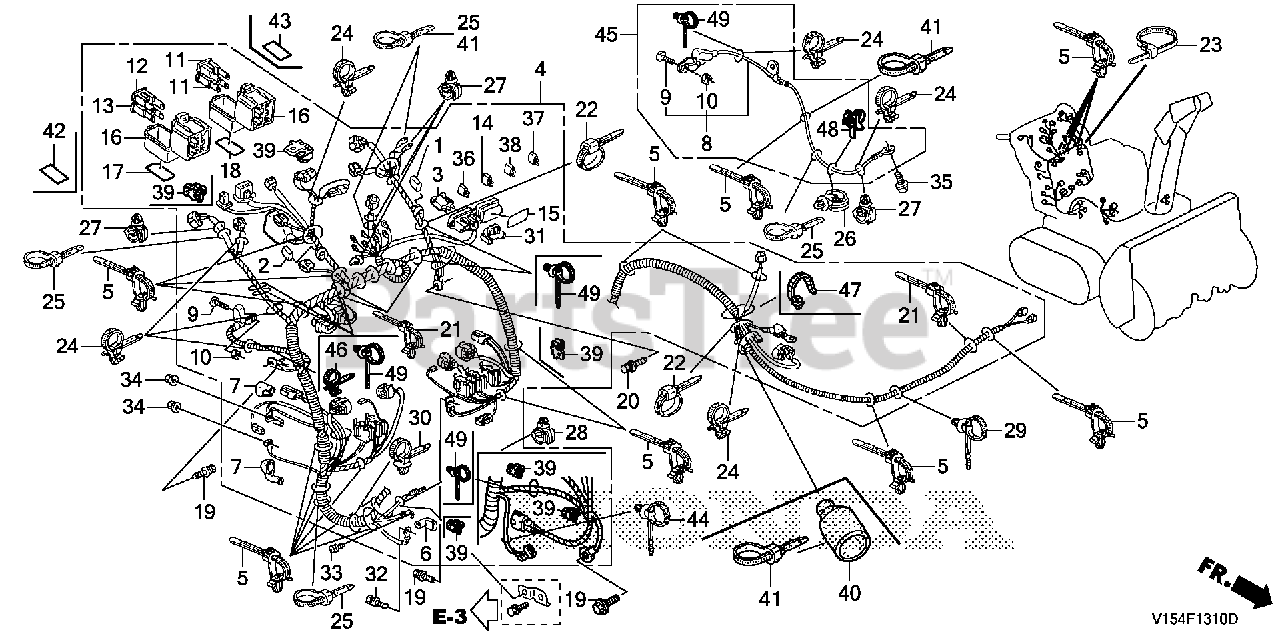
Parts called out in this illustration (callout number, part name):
4	WIRE HARNESS ASSY., MAIN
5	BAND, WIRE HARNESS
9	BOLT, BATTERY TERMINAL
10	NUT, BATTERY TERMINAL
11	FUSE (80A) (BLOCK)
12	FUSE, BLOCK (70A)
15	LABEL, BLADE FUSE
16	CASE, MAIN FUSE
17	MARK, MAIN FUSE
18	MARK, MOTOR FUSE
19	BOLT, GROUND (6X16) (WASHER 12.5MM) (ZN)
20	BOLT (6X19 SN)
21	BAND, WIRE HARNESS (150MM) (NATURAL) DUAL QTY = (2) (SINGLE)
22	BAND, WIRE (95MM)
24	STRAP, CABLE (105MM) *NH1* (Honda Code 1685536). (BLACK)
25	BAND, SUCTION HOSE (BLACK)
27	CLIP, WIRE HARNESS (25MM)
31	CLIP, CONNECTOR HOLDER (BROWN)
35	BOLT, FLANGE (6X10)
36	FUSE, MINI (5A)
37	FUSE, MINI (15A)
39	CLIP, CONNECTOR (DARK GREEN)
40	COVER, CONNECTOR (NOT AVAILABLE)
41	BAND, WIRE (165MM) (BLACK)
45	CABLE, BATTERY GROUND
46	STRAP, CABLE (118MM) *NH1L* (Honda Code 1170653). (BLACK)
47	CLIP, HARNESS BAND (164.5MM) (BROWN)
48	CLIP, BAND HARNESS (162.7MM)
49	CLIP, HARNESS BAND (145MM) (BLACK)
